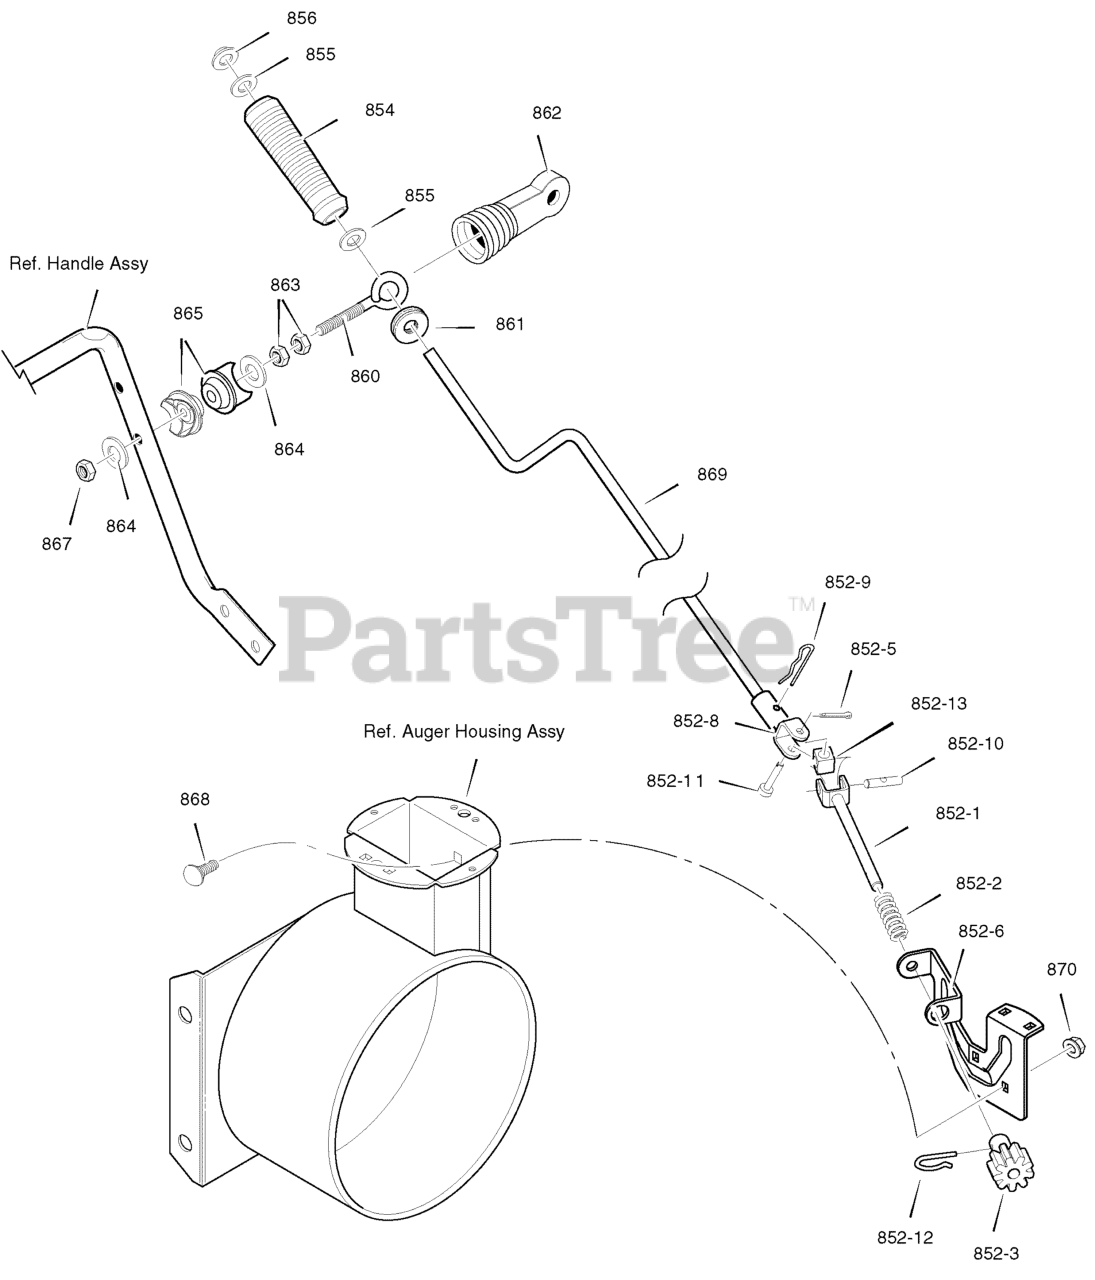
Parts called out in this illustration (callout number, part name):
852-1	ASSEMBLY, YOKE & ROD
852-3	GEAR, CHUTE ROTATION 9T
852-5	PIN, COTTER
852-6	BRACKET, CHUTE GEAR
852-8	ASSEMBLY, YOKE ADAPTER YZ
852-9	PIN, HAIR
852-10	PIN, UNIVERSAL JOINT
852-11	PIN, CLEVIS
852-12	PIN, HAIR
852-13	HOUSING, UNIVERSAL
854	KNOB, SLEEVE
855	FLATWASHER
856	NUT, PUSH ON 3/8"
860	EYE BOLT 3/8-16X6.50
861	GROMMET, EYE BOLT
862	BOOT, EYE BOLT
863	NUT, 3/8-16 HEXJAM
864	FLATWASHER .406X.81X.066
865	ADAPTER, BOOT
867	NUT, 3/8-16 HEXNYL
868	BOLT, CARRIAGE 1/4-20 X 1.00
869	CRANK, ASSY CHUTE
870	NUT, 1/4-20
